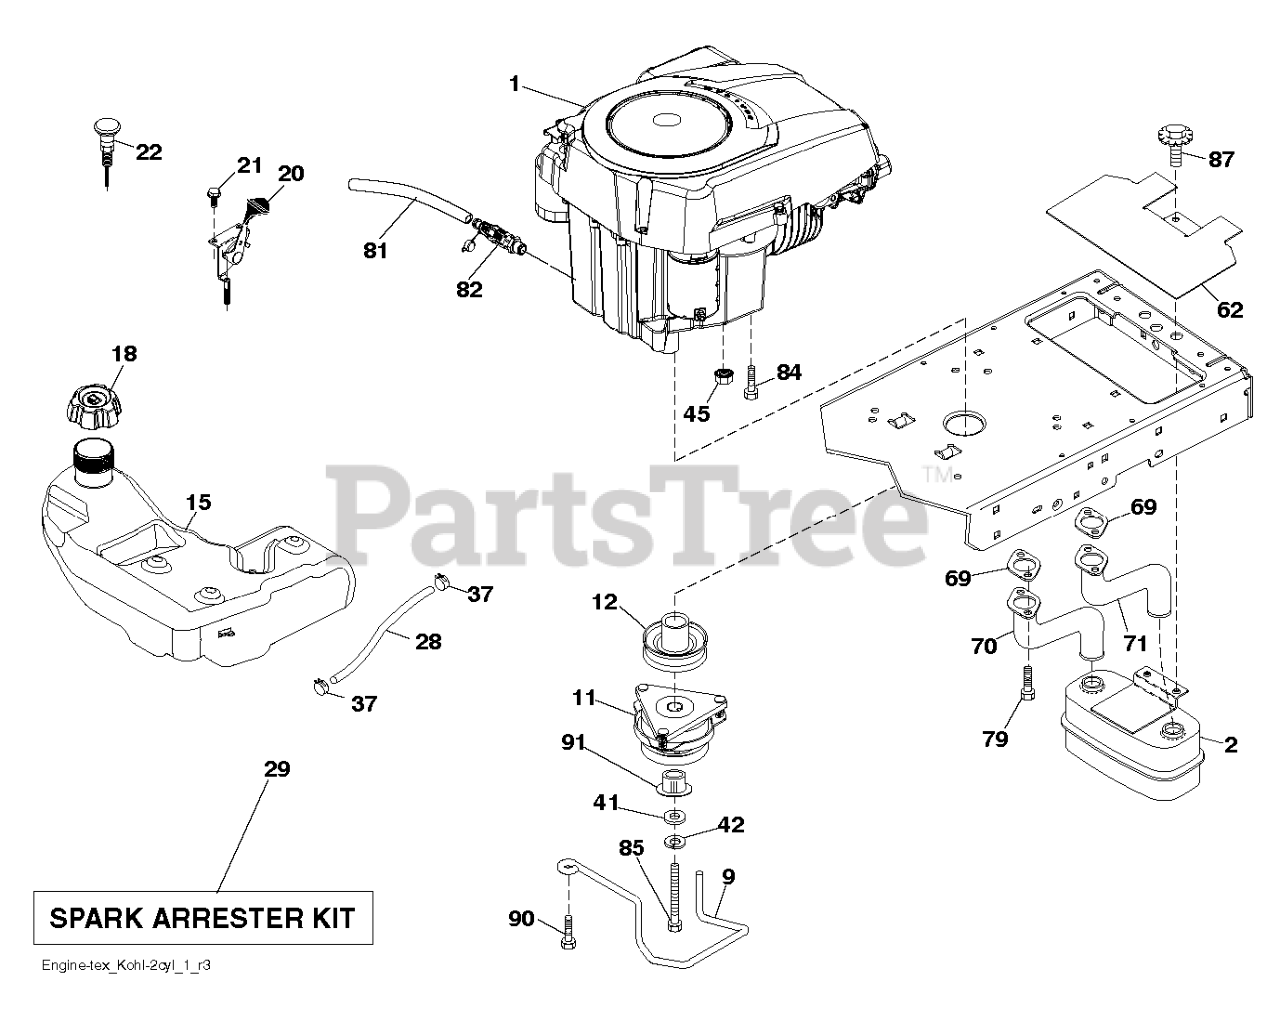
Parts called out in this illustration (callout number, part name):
2	MUFFLER.TWIN.CYL.LOW.TONE
9	KEEPER.BELT.ENGINE.4.2
11	CLUTCH MZ ZTR GT.48/54"1.125"
12	PULLEY ENGINE
15	TANK.FUEL.4GAL
18	CAP.FL.R.3'N/CARB.H.CROWN.498
20	THROTTLE CONTROL
21	SCREW.#10 X 0.750.BOS
22	CONTROL.CHOKE.ERGO.PUSH-IN.BLA
28	REPL BY 532 00 85-43
29	KIT.SPARK ARRESTOR 794945 B&S
37	HOSE CLAMP
42	LOCKWASHER
45	NUT
62	SHIELD.HEAT.MUFFLER
69	GASKET.EXHAUST.KOHL.CV18-CV26
70	RP.PIPE-EXHAUST LH
71	RP.PIPE-EXHAUST RH
79	SCREW.SOCKET HD.5/16-1
81	TUBE, DRAIN OIL ASM.
82	VALUE.OIL.DRAIN
84	SCREW 3/8-16X1
85	BOLT HEX 7/16-20 X 3.75 GR. 5
87	BOLT.5/16-18UNCX1.W/SEMS.BLK
90	SCREW 3/8-16X1
91	BUSHING.1.375OD
